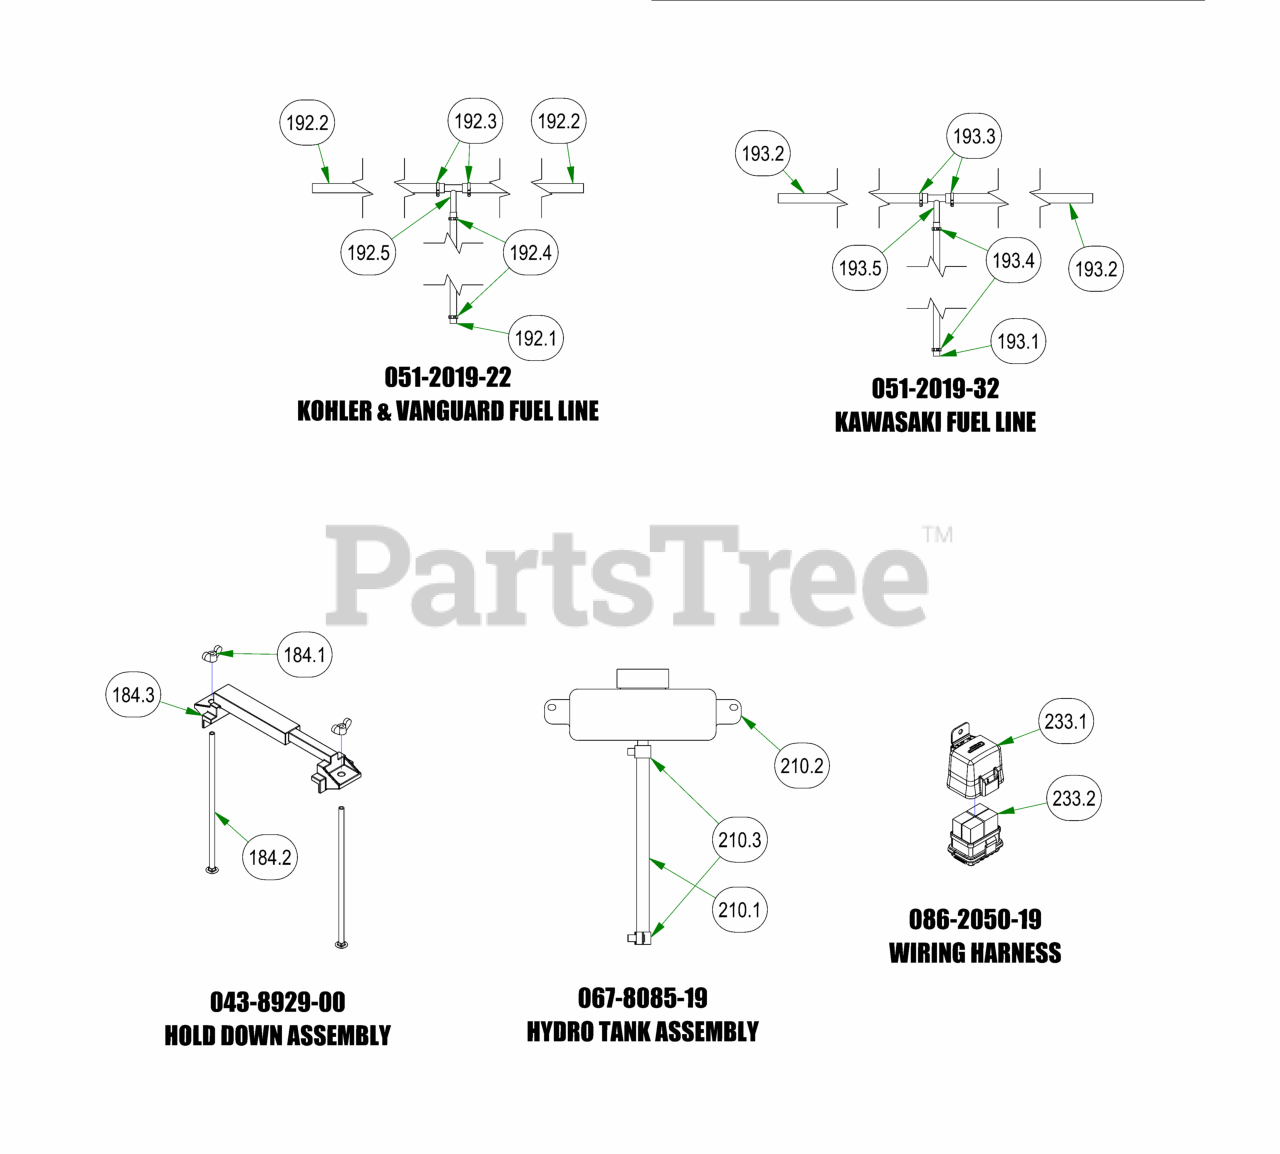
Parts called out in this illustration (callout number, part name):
184	Hold Down Assembly
184.1	1/4-20 WING NUT FORGED (TYPE A) LIGHT SERIES ZINC
184.2	1/4-20 X 8 CARRIAGE BOLT (MIN 6" THREAD) ZINC
184.3	Battery Hold Down
192	2019 Rebel Rogue Renegade Fuel Line for Vanguard & Yamaha
192.1	1/4" Fuel Line Hose
192.2	5/16" fuel line hose
192.3	5/16 Fuel Line Clamp
192.4	1/4 Fuel Hose Clamp
192.5	5/16 x 5/16 x 1/4 Fuel Line T
193	2019 Rebel Rogue Renegade Fuel Line for Kawasaki
193.1	1/4" Fuel Line Hose
193.2	5/16" fuel line hose
193.3	5/16 Fuel Line Clamp
193.4	1/4 Fuel Hose Clamp
193.5	5/16 x 5/16 x 1/4 Fuel Line T
210	2019 Rebel Hydro Tank Assembly
210.1	5/8 Braided Hose
210.2	Expansion Tank for Outlaw
210.3	5/8 Wire Clamp-Outlaw Only
226.9	2022 Rebel Control Panel
227.1	2022 Rebel Control Panel
233	2019 Wiring Harness-Rebel/Rogue
233.1	Relay Block Cover Replacement Kit
